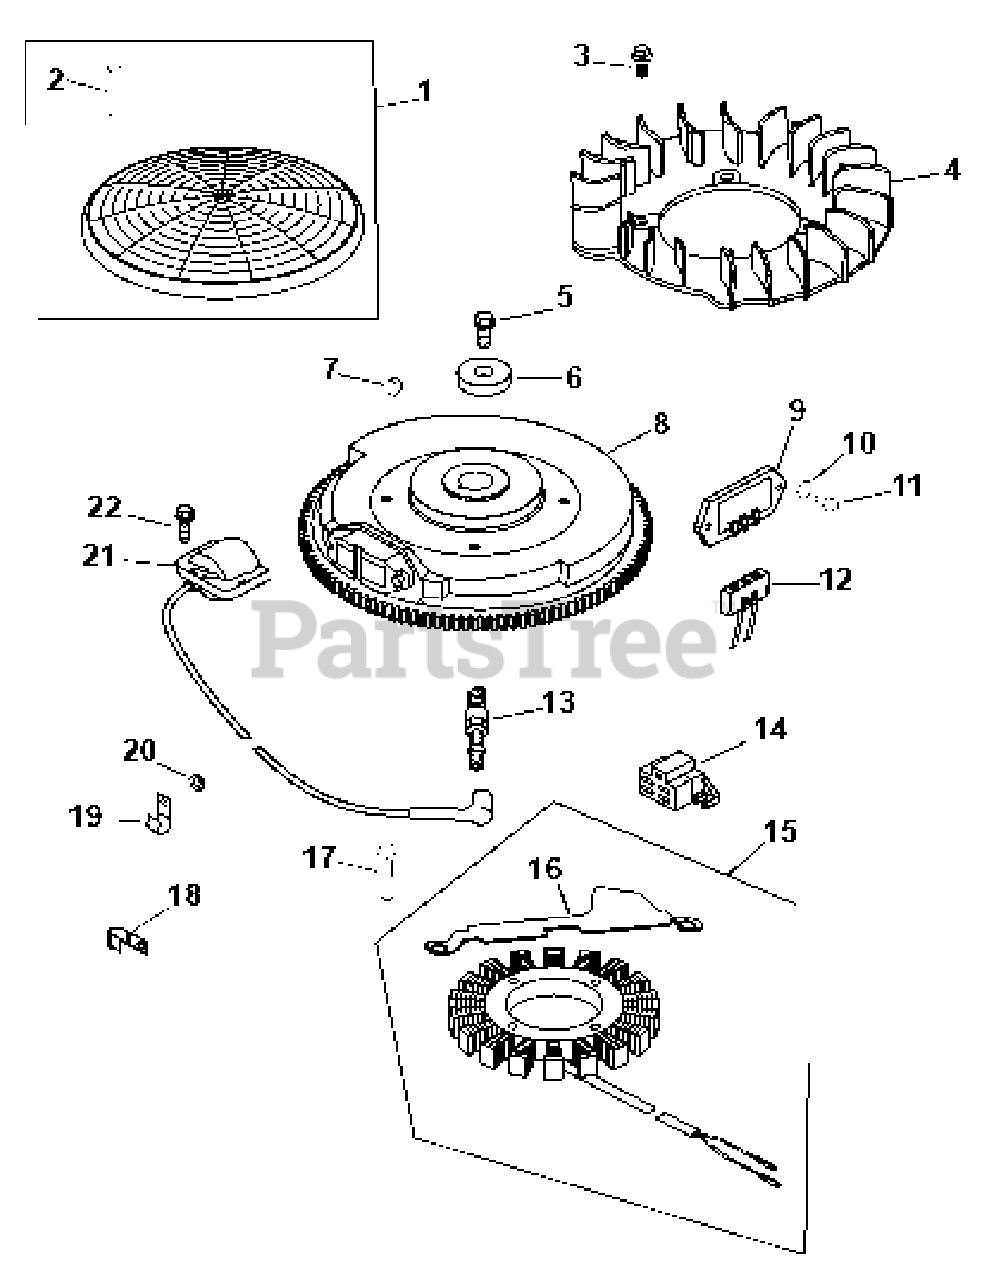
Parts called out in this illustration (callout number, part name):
1	Grass Screen Kit
3	Shoulder Bolt
4	Fan
5	Hex Flange Screw
8	Flywheel
9	Regulator Rectifier
11	Hex Head Screw
12	Connector
13	Spark Plug
15	15 amp Stator
16	Stator Wire Bracket
17	Hex Head Screw
18	Cable Clip
21	Ignition Module
22	Screw
